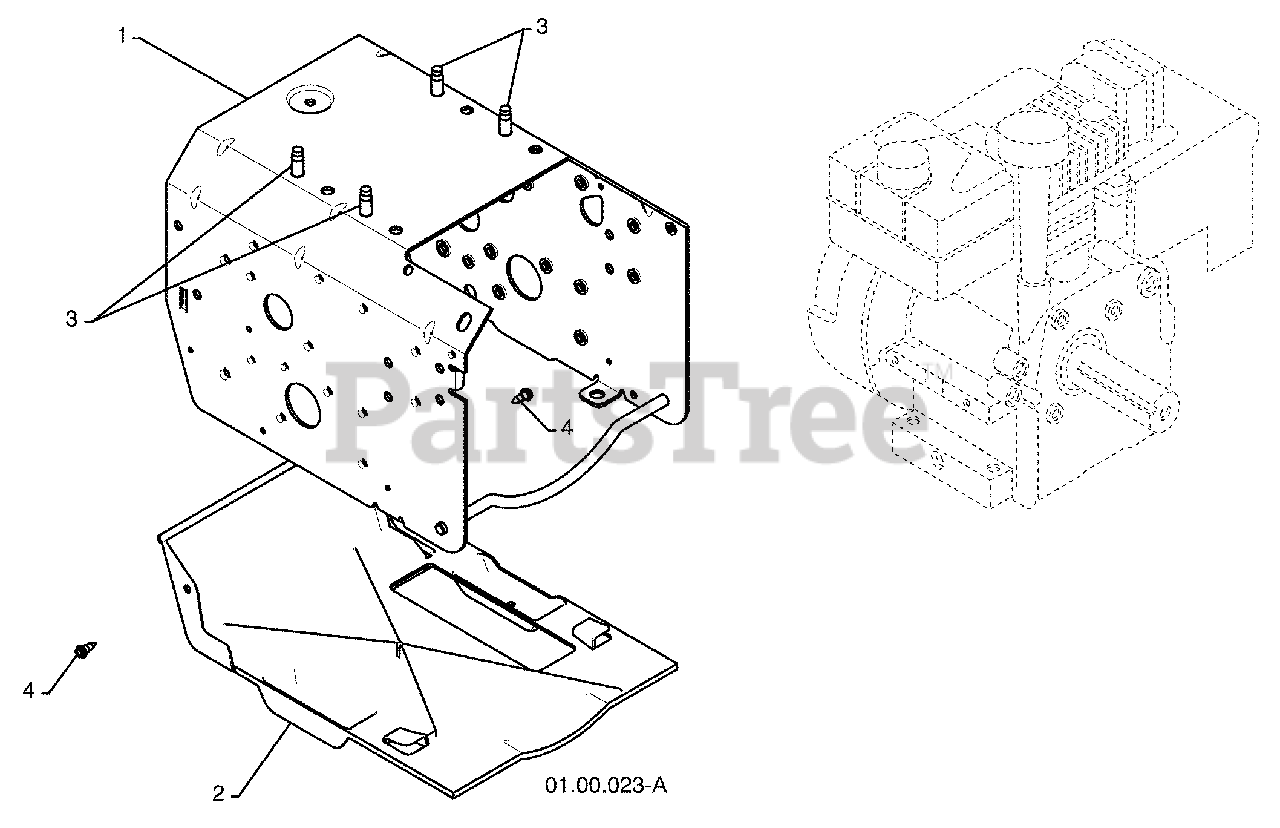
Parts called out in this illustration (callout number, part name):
2	BOTTOM PAN
3	BOLT 3/8-16
4	SCREW 10-24 X .625
